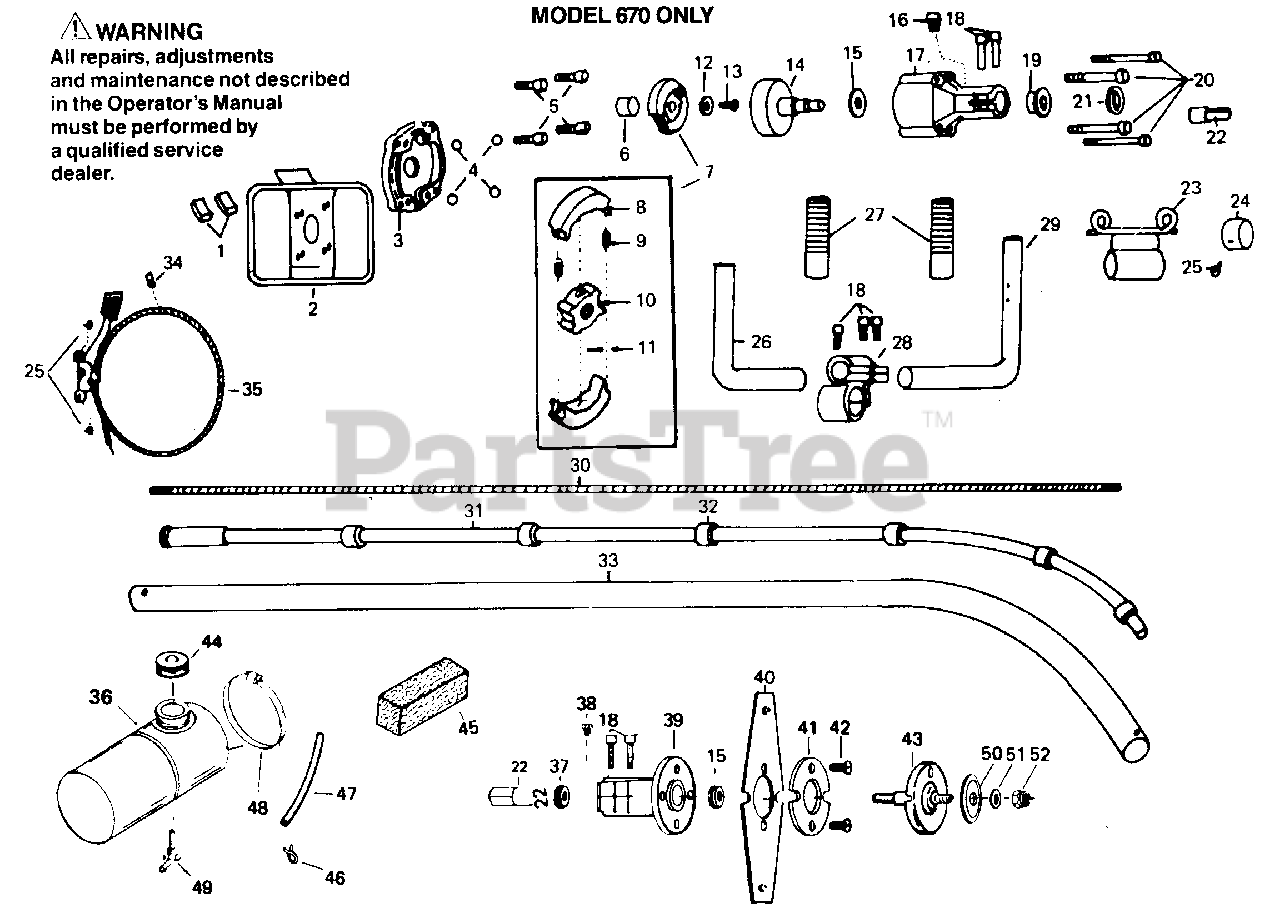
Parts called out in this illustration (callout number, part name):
1	Fuel Tank Cushion
2	GASKET DIAPHRAGM KAAZ #
3	Motor Adaptor Plate
4	Lock Washer
6	Clutch Spacer
7	Clutch Assembly (Incl. #8, 9, 10 & 11)
8	Clutch Shoe Assembly
9	Clutch Spring
10	Clutch Hub
11	Woodruff Key
12	Lock Washer
14	Clutch Drum Assembly
15	Ball Bearing, Lower
17	Clutch Housing w/Bearing & Bushing
19	Clutch Bushing
21	Drive Shaft Washer
22	End Coupling
23	Swivel Assembly
24	Swivel Keeper
26	Handle Bar (Ieft)
27	Handle Grip
28	Handle Bar Clamp
29	Handle Bar (right)
30	Flexible Drive Shaft
31	Drive Shaft Housing
32	Neoprine Guide
33	Drive Shaft Housing
34	Throttle Control Clip
35	Throttle Control Complete
36	Tank, Fuel
37	GASKET KAAZ #
39	Lower Housing
40	Blade Guard
41	Filler Plate
43	Weed Deflector Cup
44	Cap, Fuel Tank
45	Baffle, Fuel Tank
46	Clip, Fuel
47	Hose, Fuel
48	Strap, Fuel Tank
49	Fitting, Fuel
50	Washer, Lower Arbor
52	Nut, Hex - 7/16 - 20
